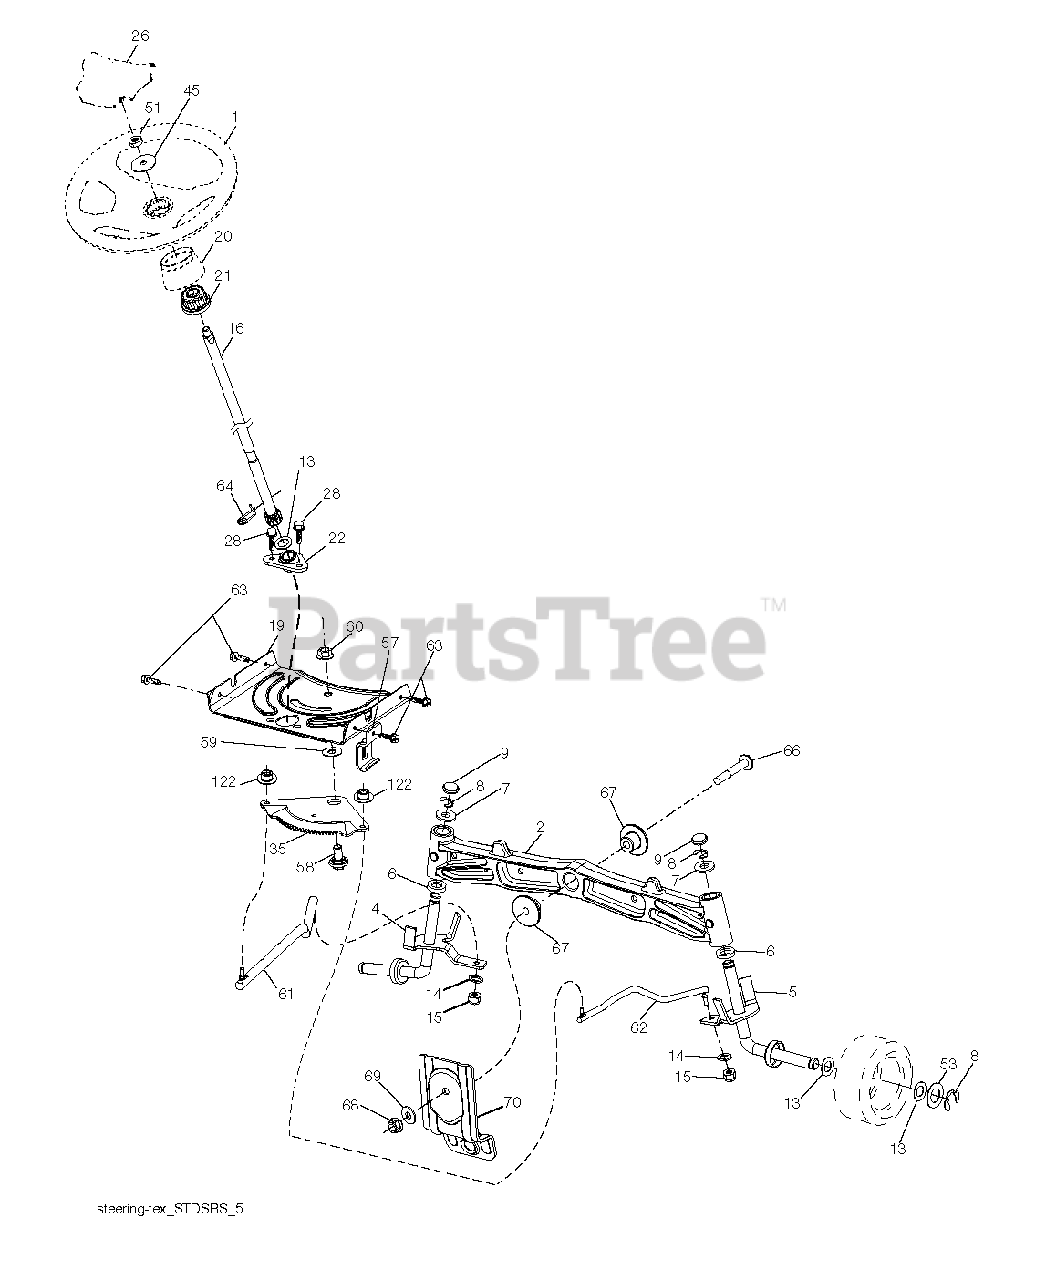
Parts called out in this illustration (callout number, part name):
1	WHEEL.STEERING.MLT.BR.YEL/OVRM
2	AXLE.CAST.IRON
4	SPINDLE.WELDED.LH.16"TEX
5	SPINDLE.WELDED.RH.16"TEX
8	RING CLIP
9	CAP.SPINDLE.BLACK
14	WASHER, LOCK 3/8
15	NUT CROWNLOCK 3/8-24
16	SHAFT, STEERING
19	PLATE.STEER.DDL.NLT/NG
20	BOOT, STEERING
21	ADAPTER, WHEEL STNG..
22	STEERING.SUPT.LOWER.
26	CAP.WHL.STRNG.MULTI.BRND.YEL
28	SCREW, 3/8-16X3/4
35	GEAR.SECTOR.PLATE.DDL.
45	WASHER 9/16"ID, 2 3/8""OD
51	NUT.HEX.1/2-20
53	WASHER.HARDENED
57	BRKT.UPSTOP.GT/LT.TEX
58	BOLT.SHOULDER.SECTOR.P
59	WASHER.THURST.SECTOR.S
60	NUT FLANGE LOCK 5/8-11
61	DRAGLINK.LH.BALLSTUD.D
62	DRAGLINK.RH.BALLSTUD.D
63	SCREW
64	RETAINER.CLIP.SPRING.S
66	BOLT HEX FGHD 7/16-14 X 3 SERR
67	BUSHING.PM.FRONT AXLE
68	NUT.LOCK.FLANGE.7/16
69	WASHER.1.5X.505X.118
70	BRKT.DECK.SUSPENSION.F
122	CAP.GEAR.SECTOR.TEX
